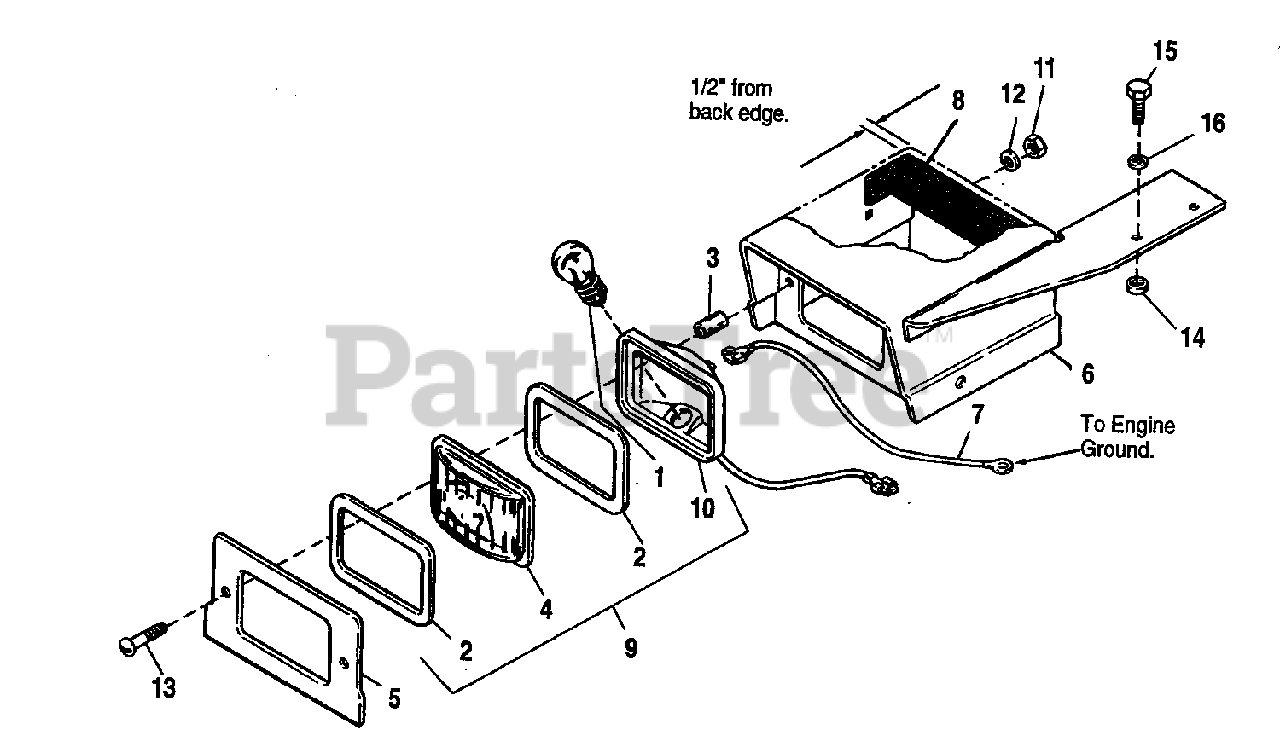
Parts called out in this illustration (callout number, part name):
4	LENS, Amber
5	SUPPORT, Light
6	COVER ASSY., Headlight
7	WIRE, Light to Ground
8	PAD, Rubber
9	LIGHT ASSY. (Incl. Ref. Nos 1, 2, 4, & 10)
10	SOCKET, Reflector
11	NUT, Hex, 1/4-20
12	LOCKWASHER, 1/4
13	SCREW, Round Hd., 1/4-20 x 1
14	WASHER, Plain, 5/16 x 1" O.D.
15	CAPSCREW, Hex Hd., 5/16-18 x 1
16	LOCKWASHER, Internal Tooth, 5/16
